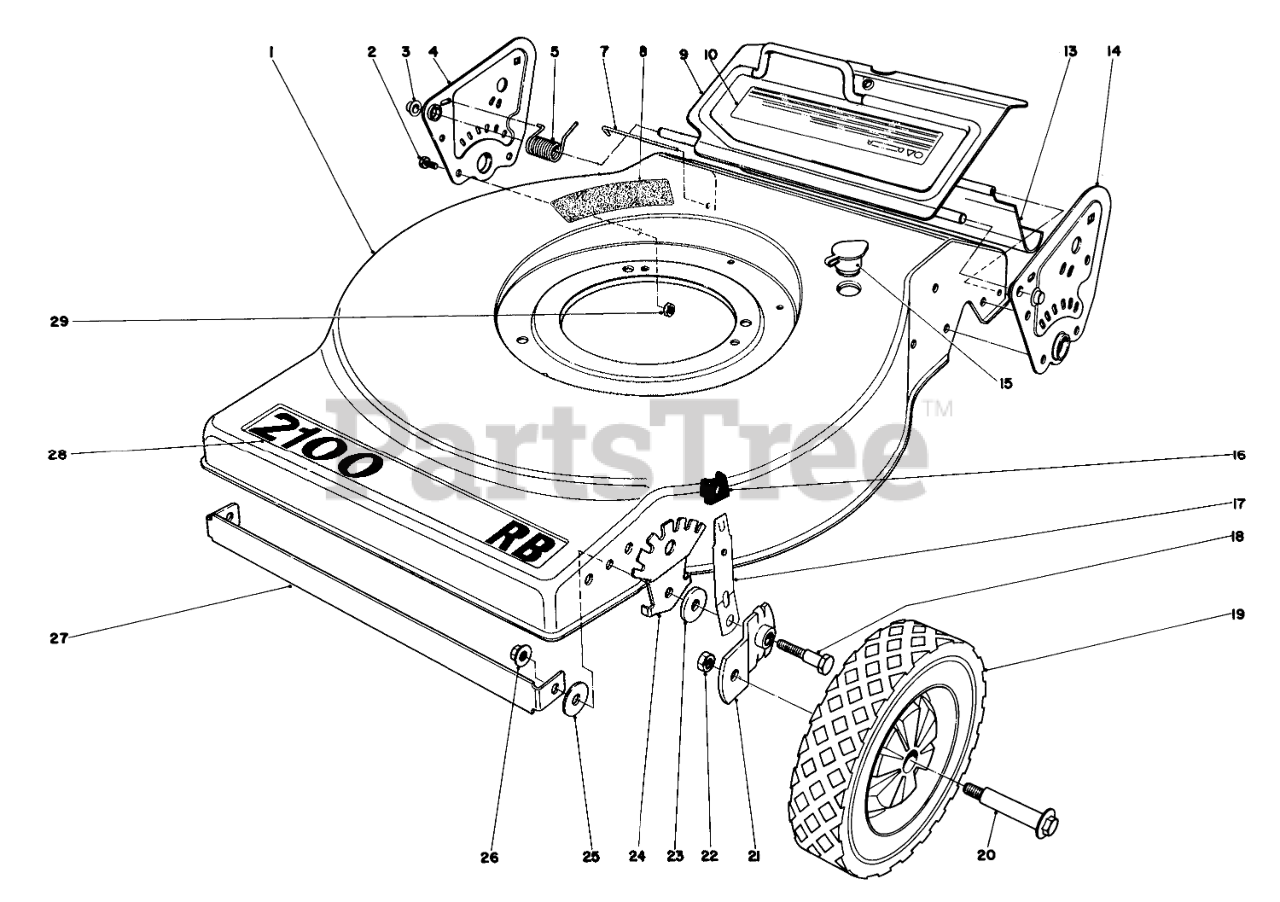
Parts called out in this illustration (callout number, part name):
1	Housing
2	SCREW-HH
3	RETAINER-PUSH ON
4	Side Plate R.H
5	TORSION SPRING
7	SHIELD ROD
8	Step Pad
9	Rear Door
10	Decal-Danger
13	SAF SHIELD REAR
14	Side Plate L.H.
15	WASHOUT PLUG
16	KNOB-ARM
17	SPRING ARM ASM
18	PIVOT SCREW
19	Wheel & Tire Assembly
20	BOLT-WHEEL
21	PIVOT ARM ASM A
22	Nut
23	PIVOT WASHER
24	Quadrant
25	WASHER
27	DECK SUPPORT
28	Decal-Deck
29	NUT-LOCK, CONE
